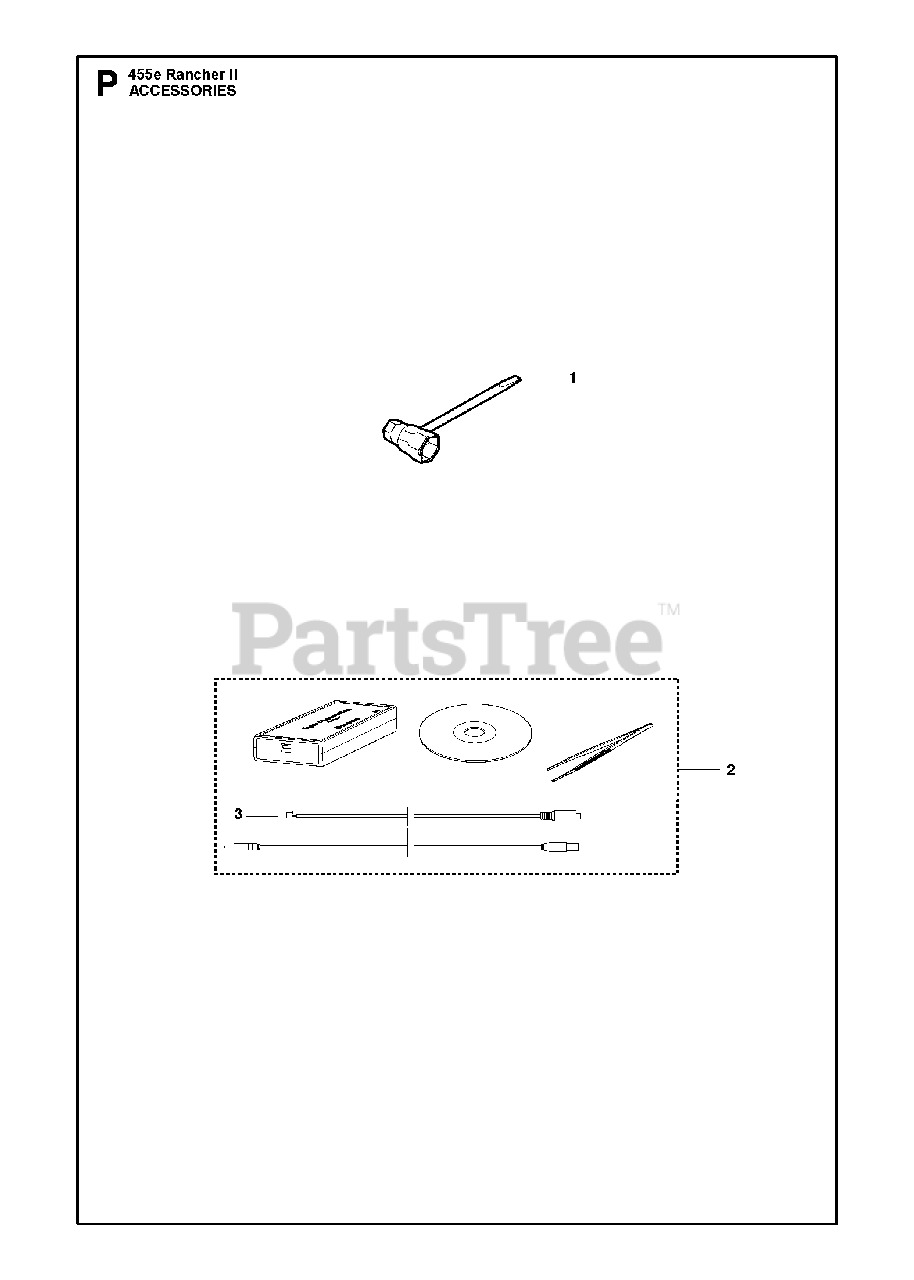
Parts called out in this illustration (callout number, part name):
1	COMBI TOOL
2	SERVICE TOOLS
3	CABLE ASSY
